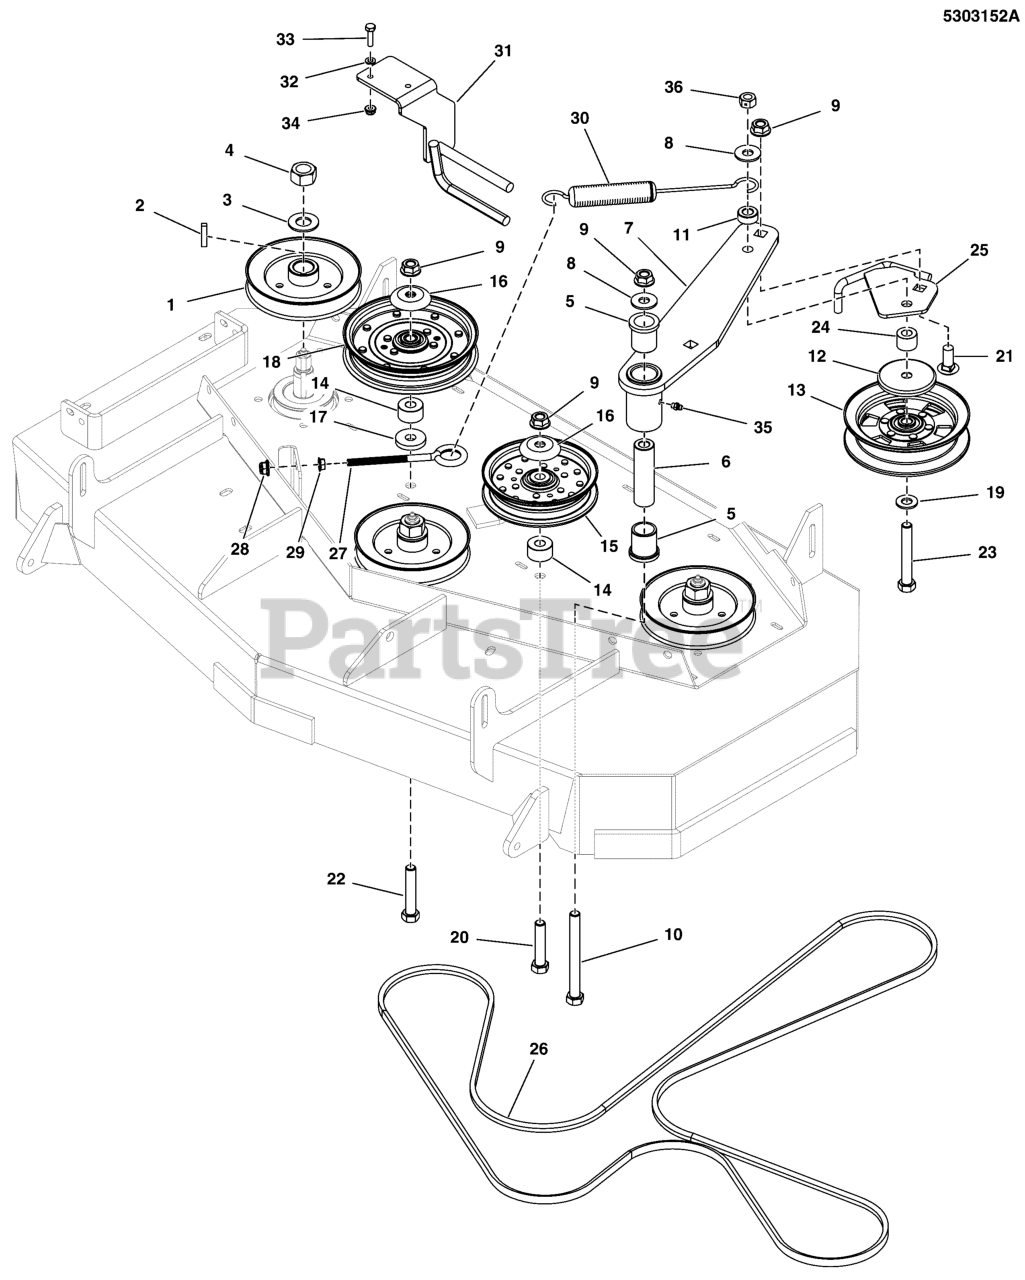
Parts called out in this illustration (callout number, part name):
1	PULLEY, 5.540OB X .985ID, SINGLE B-SEC
2	KEY, 1/4 SQ X 1-1/4
3	WASHER, 3/4 BELLEVILLE CL/ZC
4	NUT, 3/4-16 HEX
5	BUSHING, FLANGE
6	SPACER, .52 X 1.00 X 3.50
7	WELD, IDLER ARM - BLK
8	WASHER, 1/2 USS
9	NUT, Hex Flange, Nylock, 1/2-13
10	BOLT-1/2-13 X 5 GD5 CZ
11	SPACER, .52 X 1.00 X .44, CZ
12	SHIELD, BEARING, 1/2 ID X 2-7/8 OD, CZ
13	PULLEY,IDLER,BACKSIDE,NOSEAM 6.25ODX.5ID
14	SPACER, .52 X 1.25 X .70, PM, CZ
15	PULLEY, IDLER, 5" OD, 1"FACE, 5.75 FL
16	SHIELD, PULLEY BEARING, CZ
17	WASHER, .53 X 1.50 X .25
19	WASHER, 1/2 SAE
20	BOLT, 1/2-13 X 2-1/2" GD5 CZ
21	BOLT, CARRIAGE 1/2-13 X 1-1/4 GD.5
22	BOLT, 1/2-13 X 2-3/4 GD5 CZ
23	BOLT, 1/2-13 X 3-1/2, HEX HD, GD5, CZ (SV)
24	SPACER, .52 X 1.00 X .75, CZ
25	WELD, BELT GUIDE - BLK
26	BELT, 5V, 154.50"EL, ARAMID WRPD, RC
27	EYE BOLT, 3/8-16 X 6, 3THRD, 1EYE, CZ
28	NUT, 3/8-16 HEX NYLOCK FLANGE
29	NUT, 3/8-16 HEX SERRATED FLANGE
30	SPRING-EXT, 1.04 ODX10.535LGX.148WR, BLK
31	WELD, CLUTCH BELT GUIDE - BLK
32	WASHER, 1/4 SAE
33	BOLT, 1/4-20 X 1" GD5 CZ
34	NUT, 1/4-20 HEX NYLOCK FLANGE
35	GREASE FITTING, 1/4-28 STRAIGHT
36	NUT, 1/2-13 HEX SIDE LOCK
